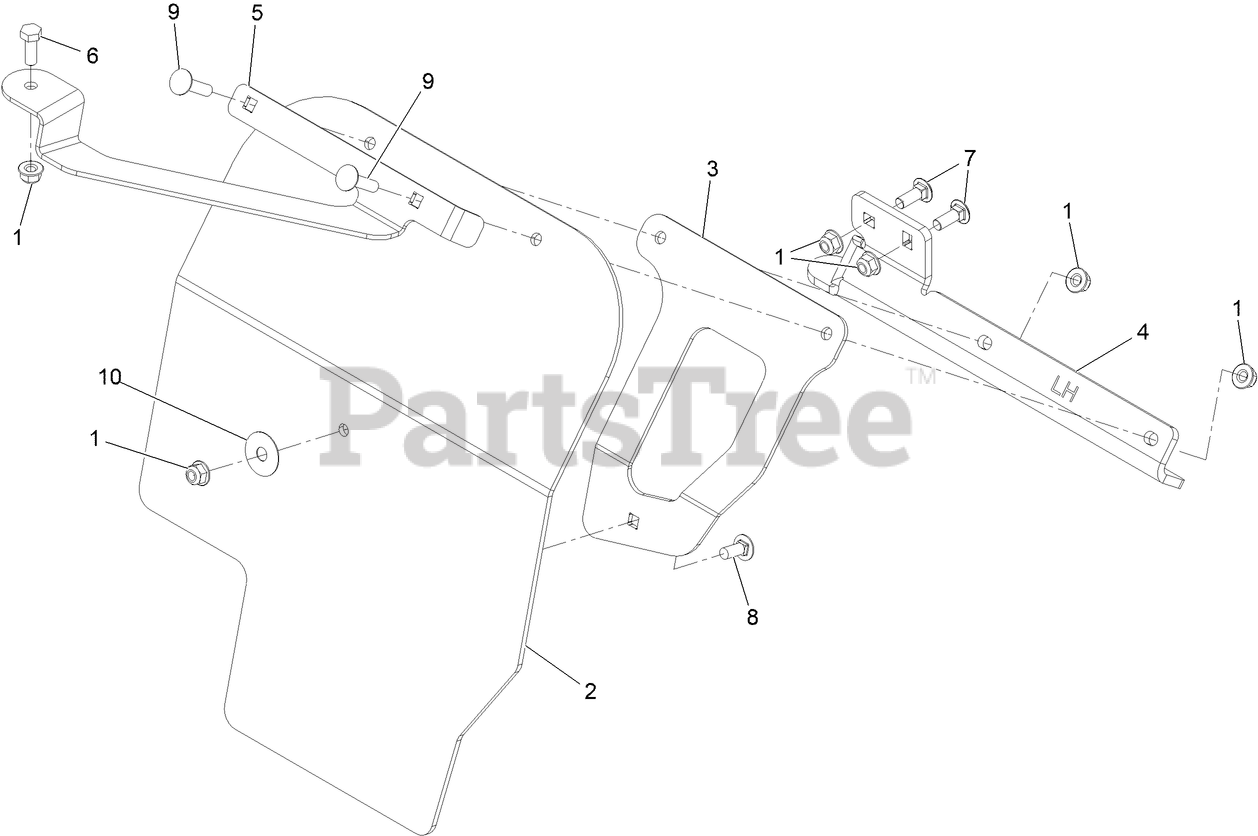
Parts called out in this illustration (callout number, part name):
1	NUT-HF, NI
2	LH MUD FLAP
3	SUPPORT, LH MUD FLAP
4	PLATE-LH MUD FLAP BRACKET
5	PLATE-LH MUD FLAP SUPPORT
6	SCREW-HH
7	SCREW-CARR
8	SCREW-CARR
9	Bolt-Carriage 5/16-18 X 1 1/4
10	WASHER-PLAIN
